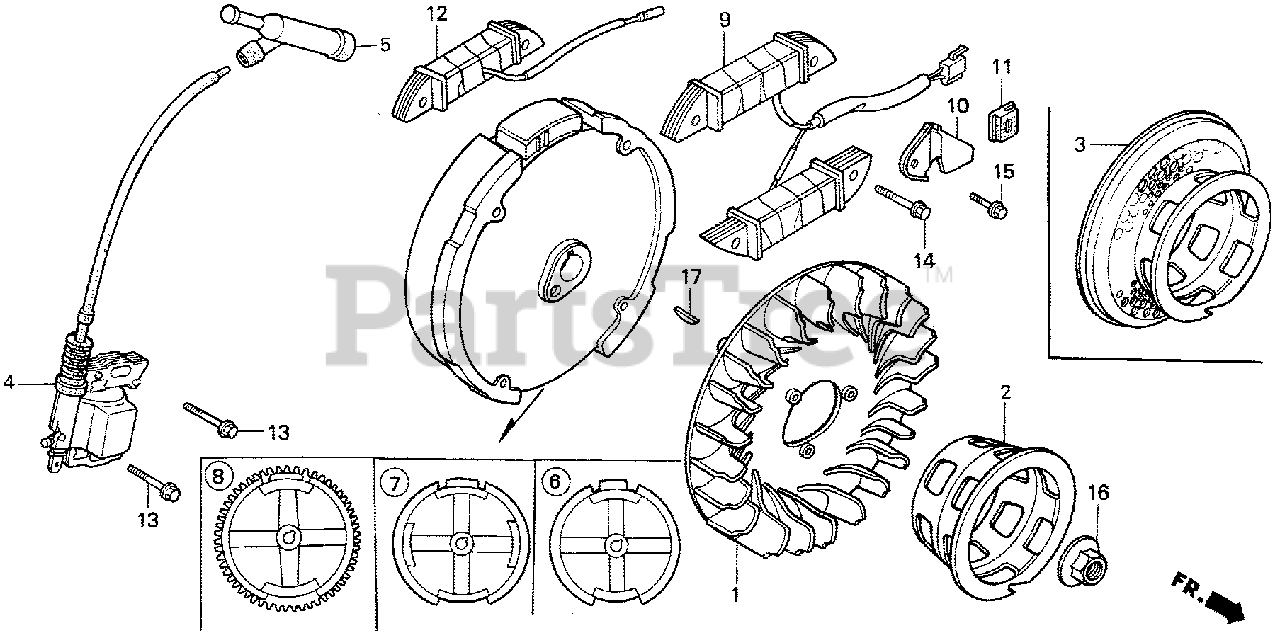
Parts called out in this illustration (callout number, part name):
1	FAN, COOLING
2	PULLEY, STARTER
4	COIL ASSY., IGNITION
5	CAP ASSY., NOISE SUPPRESSOR
6	FLYWHEEL
13	BOLT, FLANGE (6X28)
13	BOLT, FLANGE (6X25)
16	NUT, SPECIAL (14MM)
17	KEY, SPECIAL WOODRUFF (25X18)
